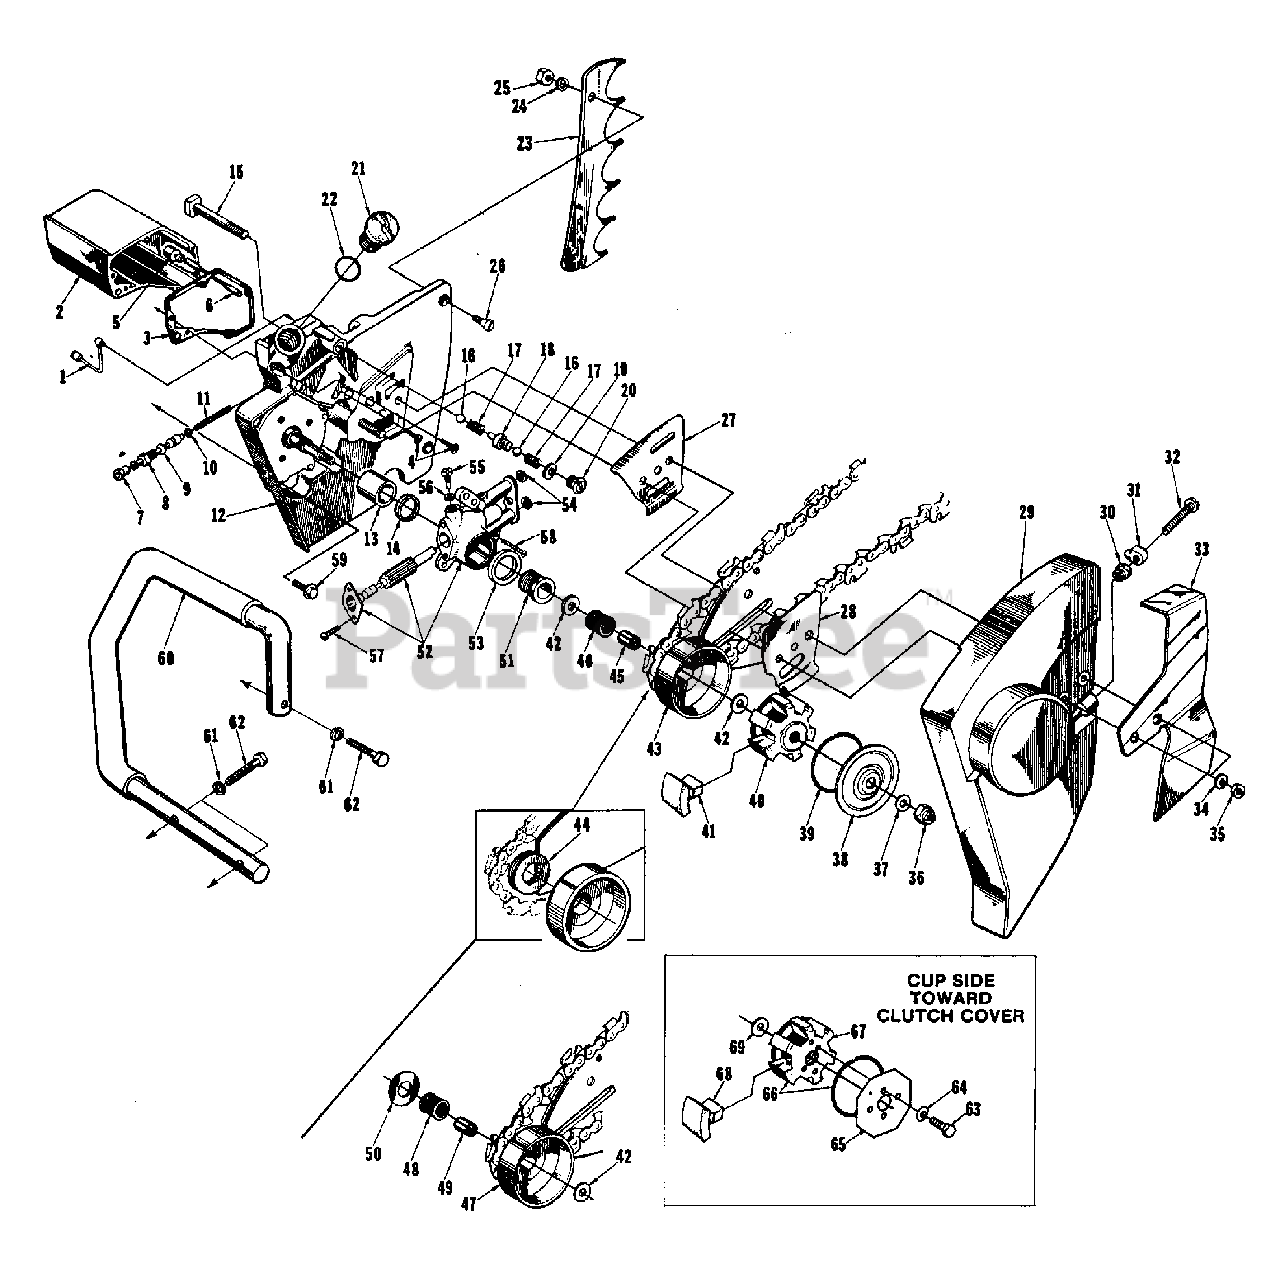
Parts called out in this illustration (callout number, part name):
1	LINE- Oil pickup
2	RESERVOIR- Oil
3	GASKET- Reservoir
4	SCREW- Fil, 8-32 x 3/4
5	FILTER- Oil
6	LINE- Oil pickup
7	CONNECTOR- Pump
8	PLUNGER- Oil pickup
9	"O" RING- Shaft
10	"O" RING- Plunger
11	SPRING- Plunger
12	DRIVECASE
13	BEARING- Needle
15	BOLT- Guide bar
16	BALL- Check
18	SEAT- Valve
20	CAP- Check valve
21	CAP- Oil
23	KIT- Spiked bumper (Long spikes)
24	WASHER- Lock, 1/4
25	NUT- Hex, 1/4-20
26	SCREW- Flat, 1/4-20 x 3/4
27	PLATE- Guide bar (inner)
28	PLATE- Guide bar (outer)
29	COVER- Drivecase
30	NUT- 5/16-18
31	PIN- Adjusting
32	SCREW- 5/16-18 x 2-1/8
33	GUARD- Chain
34	WASHER- Flat, 3/8
35	NUT- Hex 3/8-16
36	NUT- Hex, 3/8-24 (5/8" clutch)
37	WASHER- Flat (5/8" clutch)
38	COVER- (5/8' clutch)
39	SPRING- (5/8" clutch)
40	SPIDER- (5/8" clutch)
41	SHOE- Clutch (5/8" clutch)
42	WASHER- Thrust (5/8" clutch)
43	DRUM & HUB- (Rim type)
44	SPROCKET 404 pitch, 8 tooth
45	RACE- Inner
46	BEARING- Needle caged
47	SPROCKET & DRUM (open type) 404 pitch 8 tooth
48	BEARING- Needle
49	RACE- Inner
50	WASHER Thrust
51	WORM- Gear
52	PUMP- Automatic oil (short stroke)
53	SEAL Felt
54	"O" RING
55	SCREW- Cam
57	SCREW-Pan hd., (4-40 x 1/4)
58	SCREW- Hex, 8-32 x 1/2
59	SCREW- Hex, 12-24 x 3/4
60	HANDLE BAR- Flush cut
61	WASHER- Lock, 5/16
62	SCREW- Hex, 5/16-18 x 1-1/2
63	SCREW- (3/4" Clutch)
64	WASHER- (3/4" Clutch)
65	COVER- (3/4" Clutch)
66	SPRING- (3/4" Clutch)
67	SPIDER- (3/4" Clutch)
68	SHOE- (3/4" Clutch)
69	WASHER- Thrust (3/4 Clutch)
